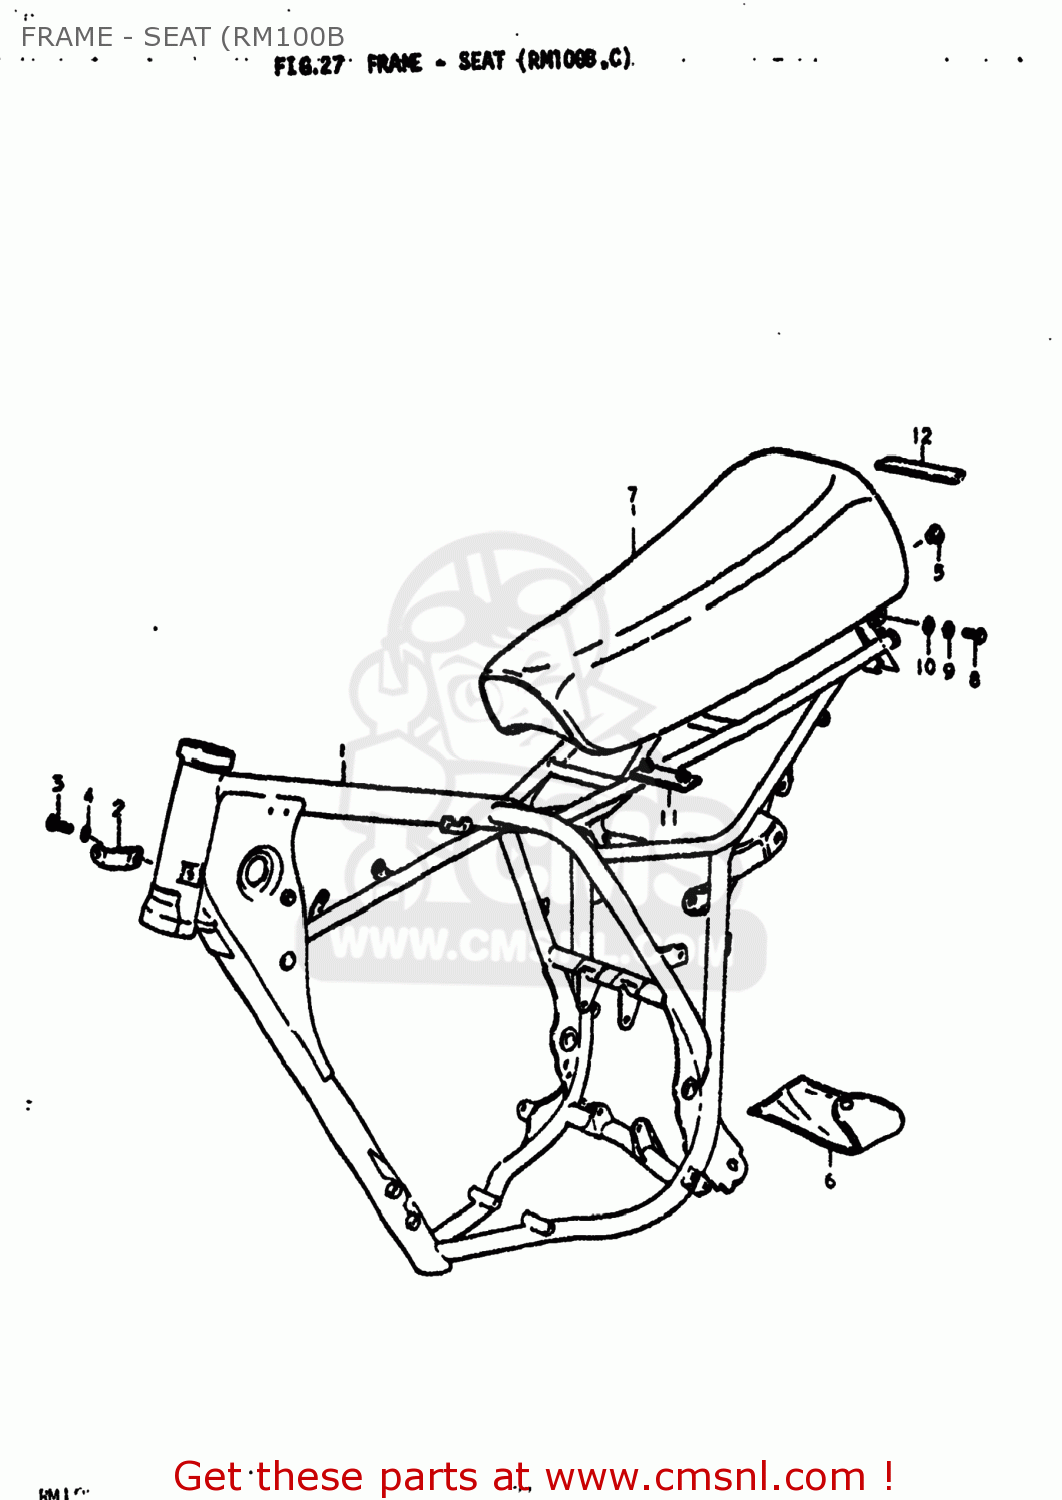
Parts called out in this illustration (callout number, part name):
1	FRAME
2	PLATE,ENGINE MOUNTING
3	BOLT
4	LOCK WASHER
5	CAP(OD:17)
7	SEAT ASSEMBLY
8	BOLT
9	LOCK WASHER
10	WASHER
11	CUSHION
12	CUSHION,FRAME
